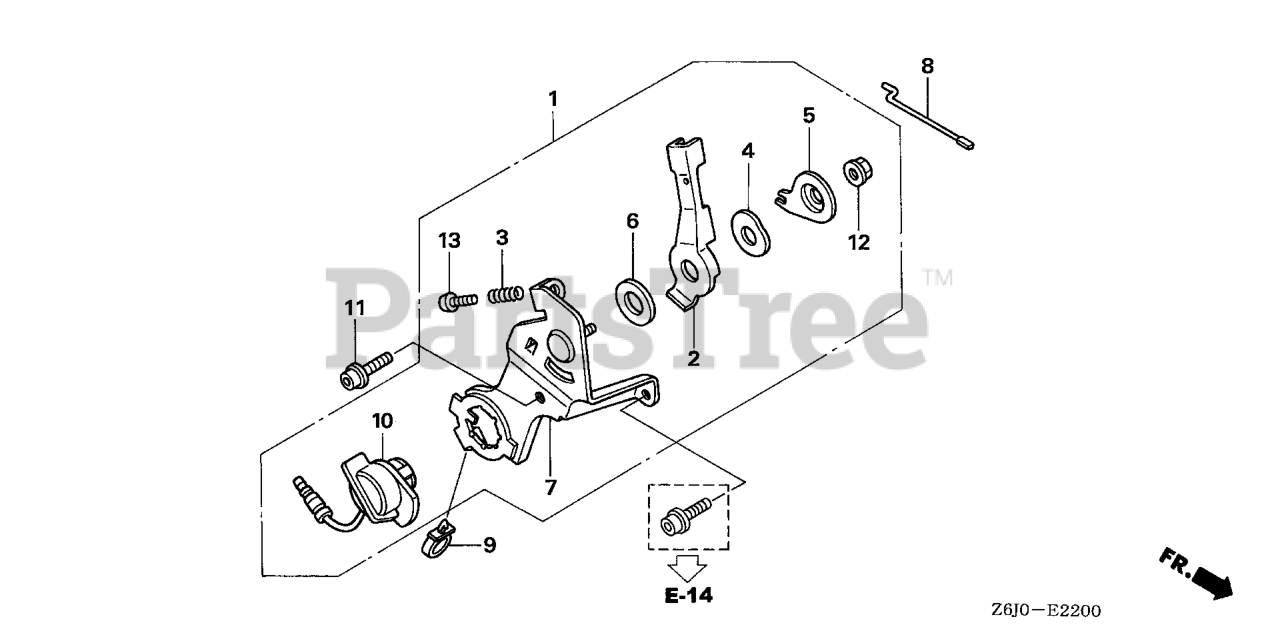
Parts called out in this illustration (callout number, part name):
1	CONTROL ASSY.
2	LEVER, CONTROL
3	SPRING, CONTROL ADJUSTING
4	SPRING, LEVER
5	WASHER, CONTROL LEVER
6	SPACER, CONTROL LEVER
7	BASE, CONTROL
8	ROD, THROTTLE
9	CLIP, IGNITION WIRE (8MM)
10	SWITCH ASSY., ENGINE STOP (TOYO DENSO)
11	BOLT, SOCKET (5X10)
12	NUT, SELF-LOCK (6MM)
13	SCREW, PAN (5X25)
